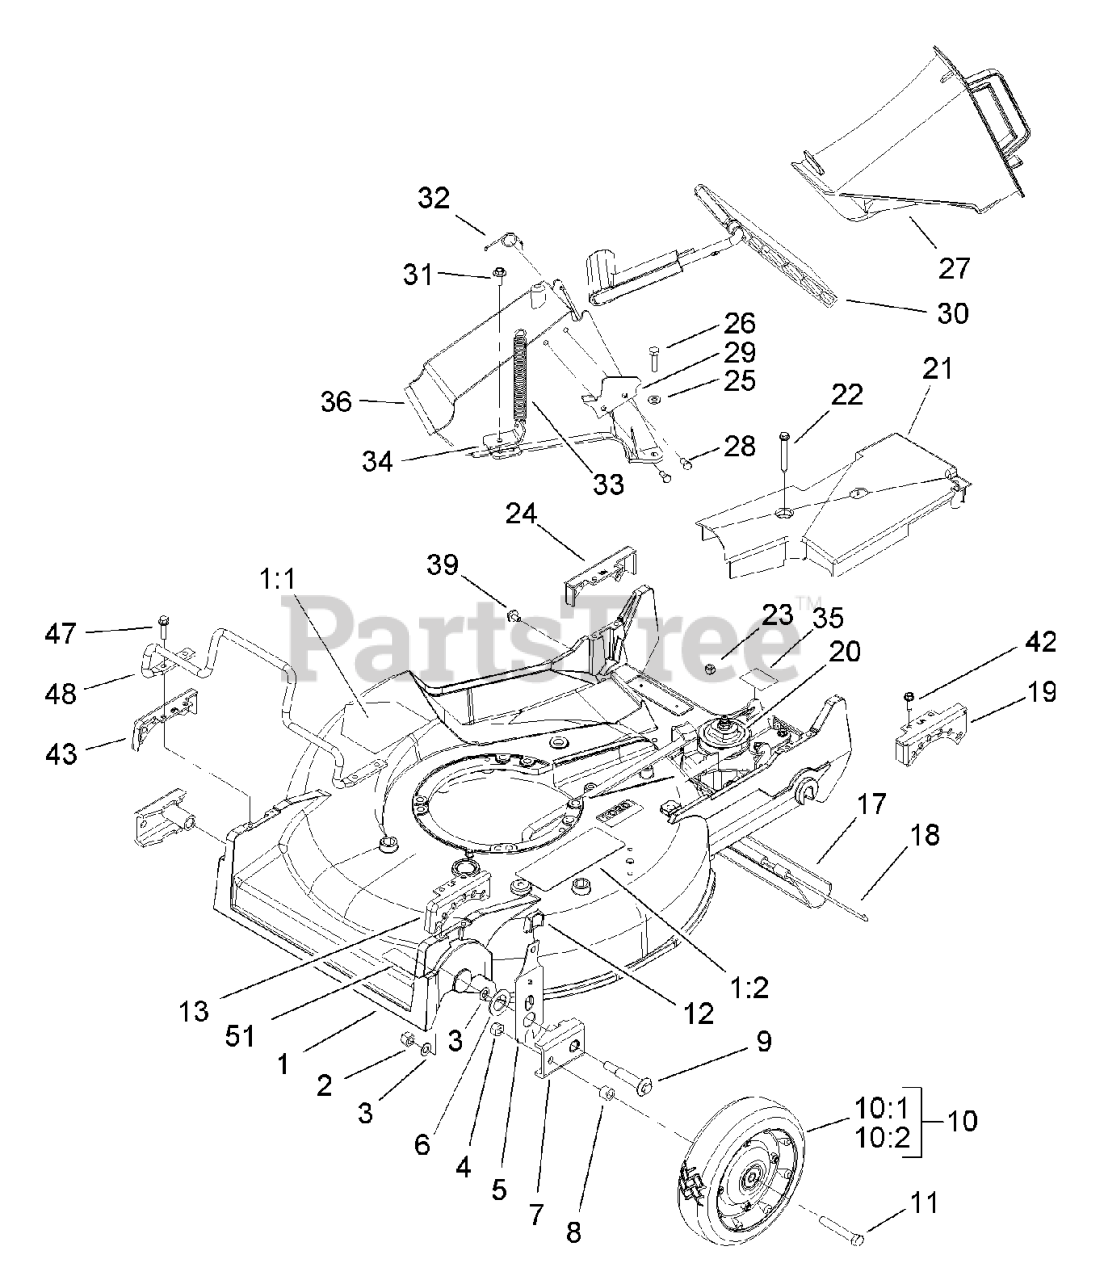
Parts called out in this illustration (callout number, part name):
1:1	DECAL-DANGER
1:2	DECAL-WARNING
2	NUT-LOCK
4	NUT-LOCK, CONE
5	FRONT SPRING ARM ASM
6	WASHER-THRUST
7	ARM-PIVOT, FRONT
8	SPACER-WHEEL
10:2	Wheel Asm
11	BOLT-CARR
12	KNOB-ARM
13	QUADRANT-FRONT, LH
18	ROD-SHIELD
19	QUADRANT-REAR, LH
21	COVER-BELT
22	SCREW-HWH
23	NUT-LOCK, NI
24	QUADRANT-REAR, RH
25	WASHER-FLAT
26	SCREW-HH
27	DISCHARGE PLUG ASM
28	SCREW-PLASTITE
29	LATCH-PLATE
30	DISCHARGE DOOR ASM
31	SCREW-HWH
32	RETAINER-DOOR
33	SPRING-DOOR
34	BRACKET-SPRING
35	Label-Grease
36	TUNNEL-DISCHARGE
39	SCREW AND WASHER ASM
42	SCREW-HWHTF
43	QUADRANT-FRONT, RH
47	SCREW-HWHTF
48	GUARD-ENGINE
51	DECAL-BLADE
